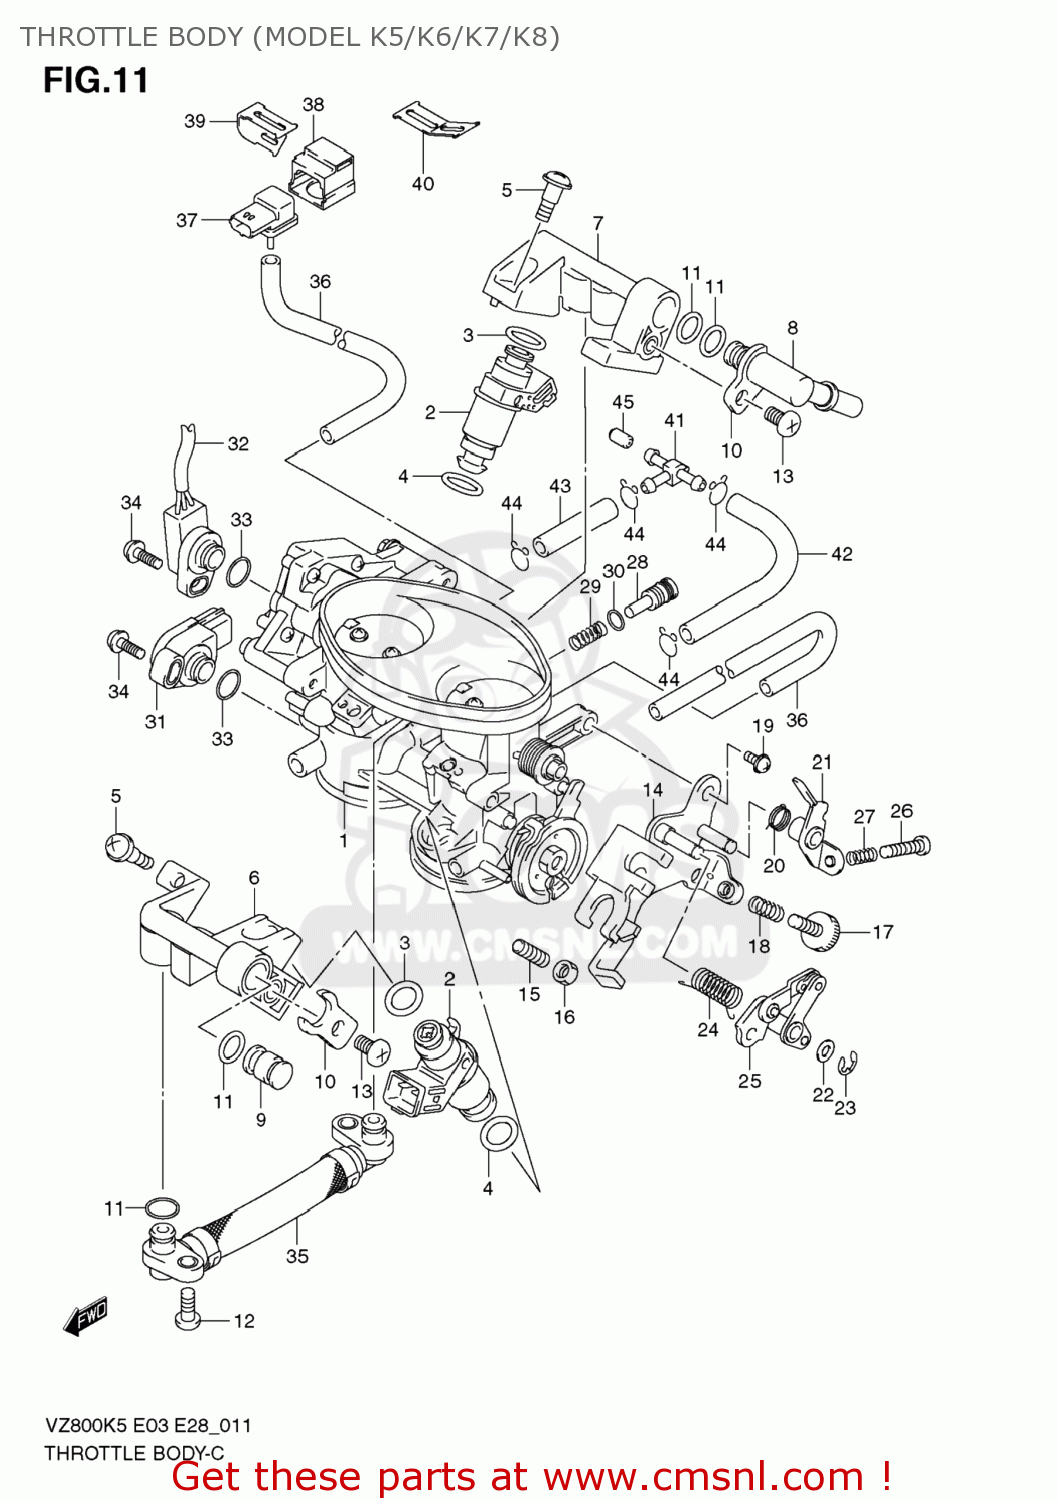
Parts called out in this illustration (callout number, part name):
1	THROTTLE BODY KIT
2	INJECTOR ASSY
3	O RING
4	O RING
5	SCREW,THROTTLE COVER
6	PIPE,FUEL
7	PIPE,FUEL
8	JOINT
9	PLUG
10	PLATE
11	O RING
12	SCREW
13	SCREW
14	PLATE,STAY
15	SCREW,STOP
16	NUT
17	SCREW,IDLE
18	SPRING
19	SCREW
20	SPRING
21	LEVER,LINK
22	WASHER
23	E CLIP
24	SPRING
25	LEVER SET,LINK
26	SCREW
27	SPRING
28	SCREW,ADJUST
29	SPRING
30	O RING
31	SENSOR ASSY,TH
32	SENSOR ASSY,TH
33	O RING
34	SCREW
35	PIPE ASSY,FUEL
36	HOSE
37	SENSOR,PRESSURE
38	HOLDER,SENSOR
39	BRACKET,BOOST SENSOR FR
40	BRACKET,BOOST SENSOR RR
41	NIPPLE
42	HOSE
43	HOSE
44	CLIP
45	PIPE
